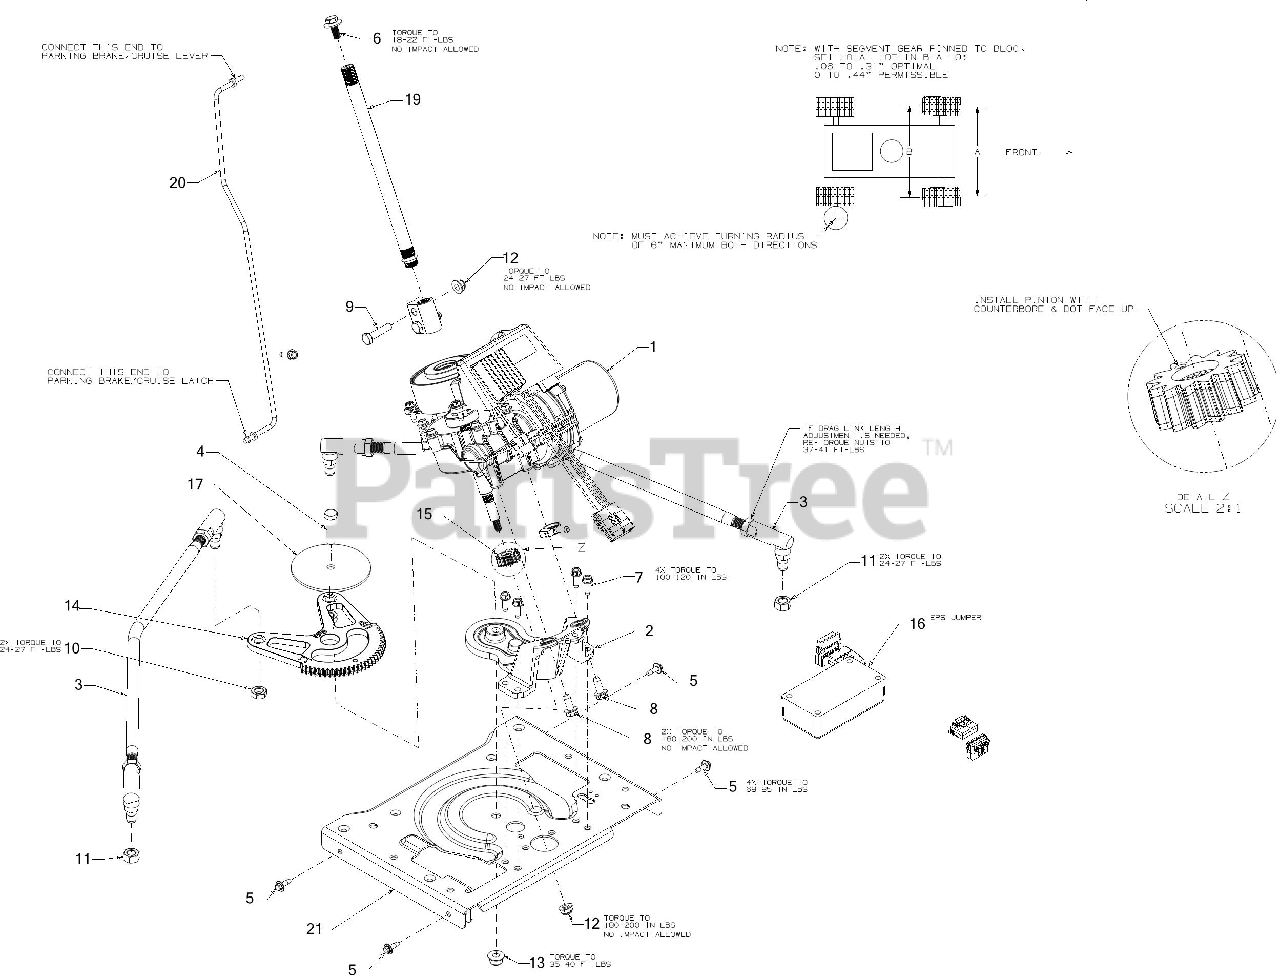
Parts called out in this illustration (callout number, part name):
1	POWER STEERING TRANSMISSION ASSEMBLY
2	STEERING MOUNTING HOUSING ASSEMBLY
3	STEERING TIE ROD ASSEMBLY
4	SCREW 3/8-16 x 1.50
5	SCREW M6-1 x .625
6	SCREW 5/16-24 x .85 GR5
7	SCREW 1/4-20 x .750
8	SCREW 5/16-18 x .750
9	BOLT 5/16-18X1.375 GR5
10	JAM NUT 7/16-20
11	HEX NUT 7/16-20
12	FLANGE LOCK NUT 5/16-18
14	STEERINGG SEGMENT GEAR
15	STEERING PINION GEAR 13T
16	VOLT PROTECTOR HARNESS EPS PURPLE
17	FLAT WASHER .385 x 3.75 x .120 THK
18	GREASE-#251 EP (NOT SERVICEABLE)
19	STEERING SHAFT 10.28
20	CRUISE/BRAKE ROD
